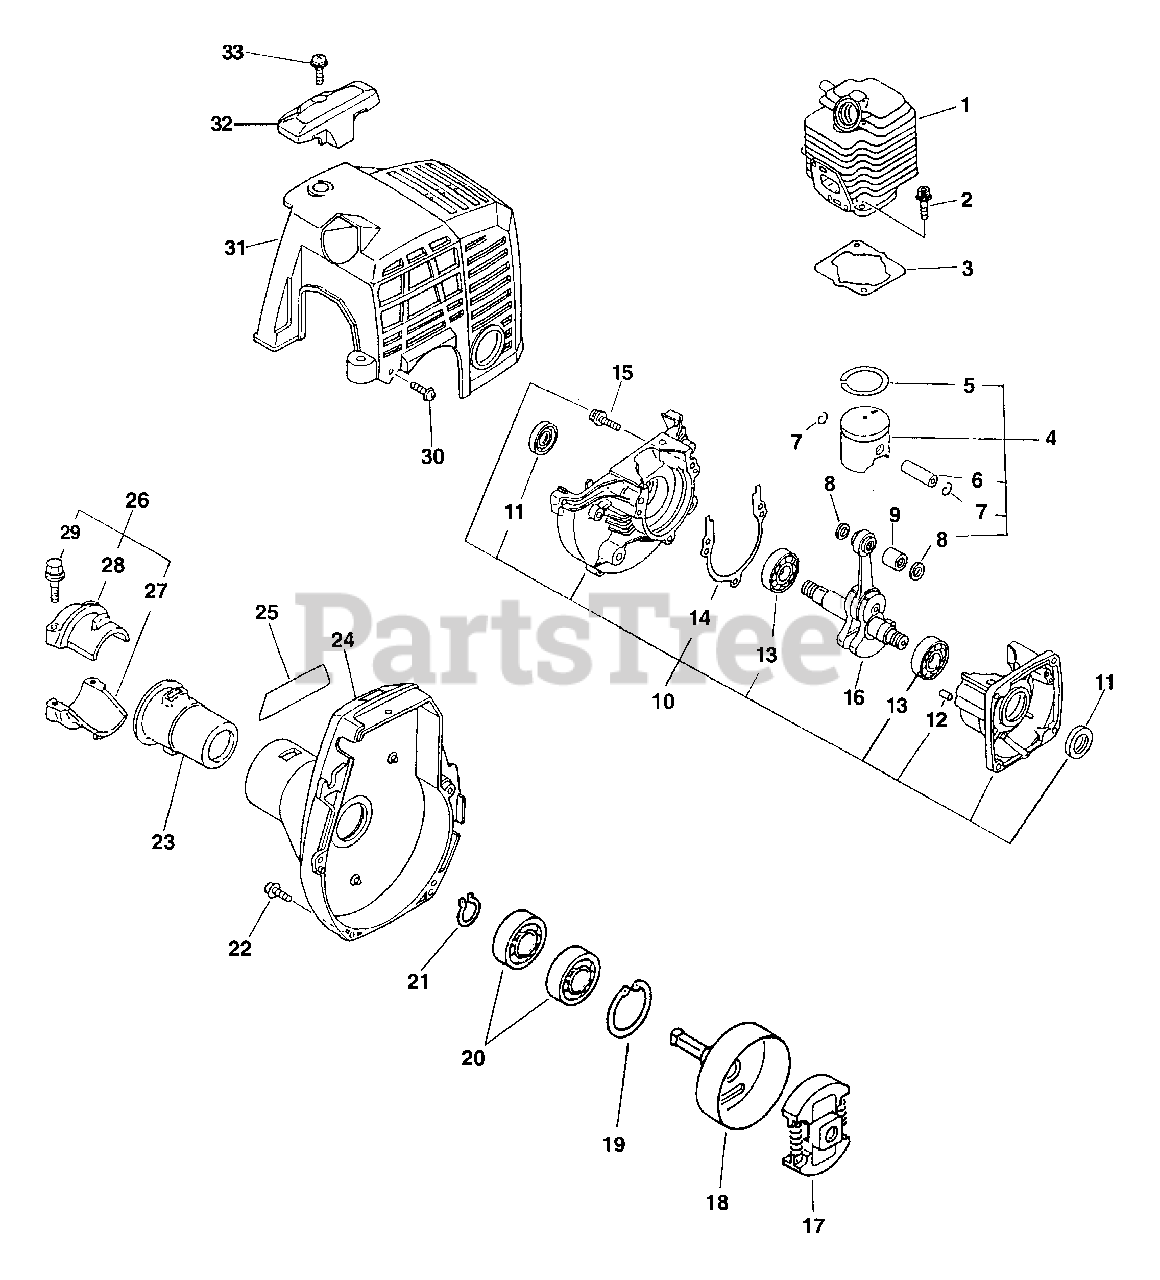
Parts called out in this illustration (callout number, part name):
1	CYLINDER KIT
2	SCREW - 5X22
3	GASKET, CYLINDER
4	PISTON KIT
5	RING, PISTON
6	PIN, PISTON
7	RING, RETAINING
8	SPACER, PISTON
9	BEARING, NEEDLE
10	CRANKCASE KIT
11	SEAL, OIL
12	PIN - LOCATING
13	BEARING, BALL - 6201
14	GASKET, CRANKCASE
15	SCREW - 5X28
16	CRANKSHAFT ASSY
17	CLUTCH ASSY
18	DRUM, CLUTCH
19	RING, RETAINING - 28
20	BEARING, BALL - 6001
21	RING, RETAINING - 12
22	SCREW - 4X16
24	CASE, FAN
25	LABEL - MODEL
26	MAIN PIPE CLAMP KIT
27	CLAMP, MAIN PIPE - LOWER
28	CLAMP, MAIN PIPE - UPPER
29	BOLT - 5X25
30	SCREW - 4X16
31	COVER, ENGINE
32	GUARD - TOP
33	SCREW - 5X16
34	SHORT BLOCK -- SB1024
35	GASKET KIT
